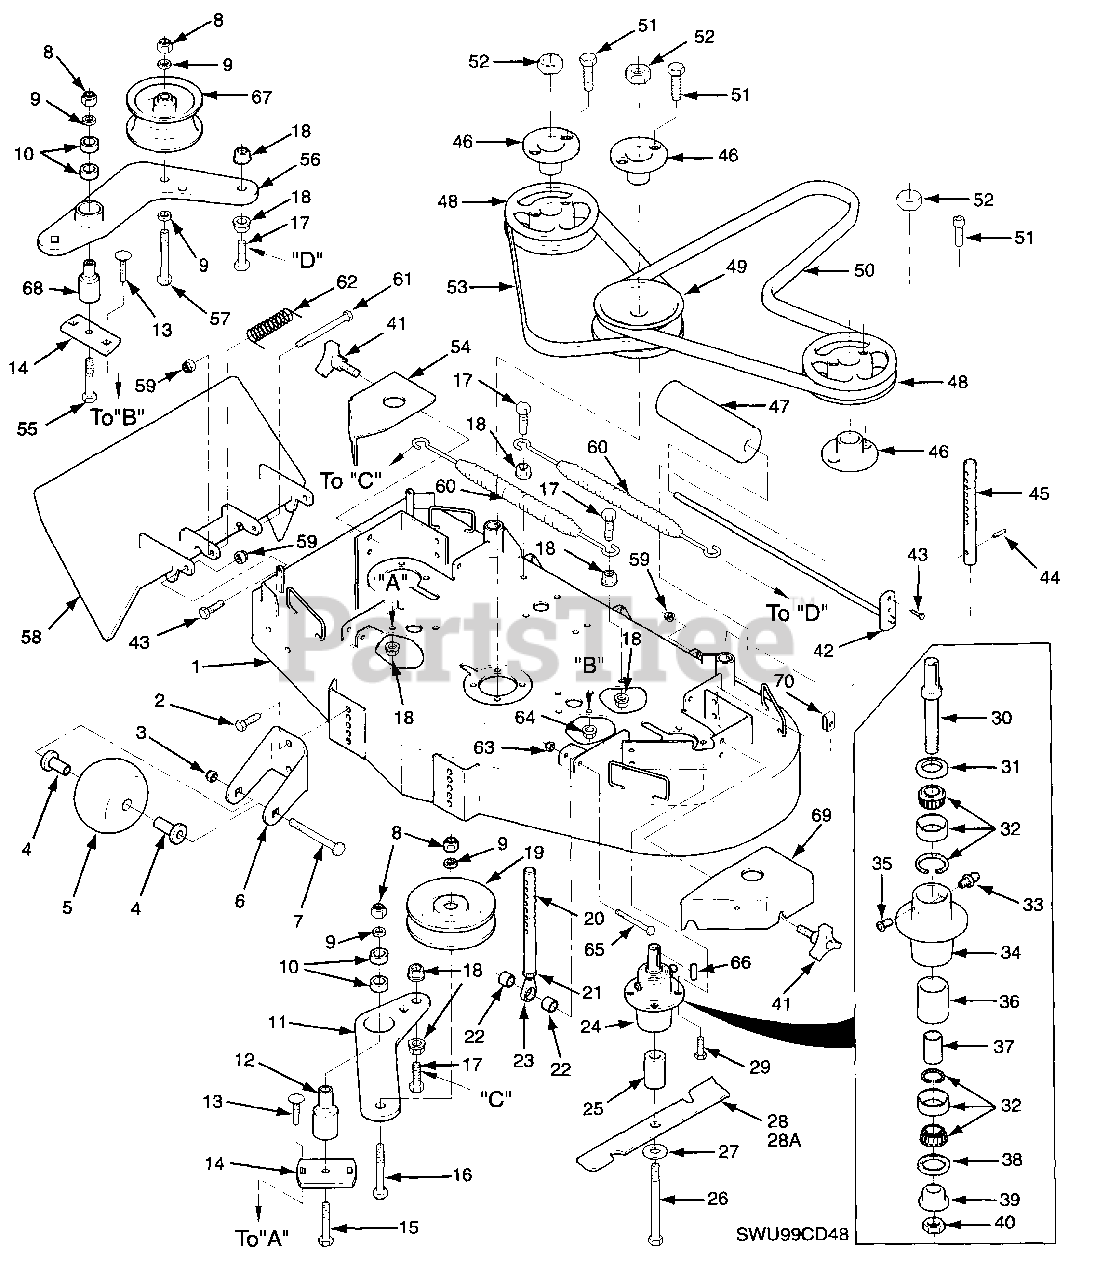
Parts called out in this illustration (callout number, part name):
1	Cutter Deck With Decals
2	Capscrew, 3/8-16 x 1.0" Serrated Flange
3	Lock Nut, 3/8-16 Center Lock
4	Bushing, 376 ID Oilite
5	Wheel, Anti-Scalp
6	Bracket, Anti-Scalp Wheel
7	Bolt, Carriage 3/8-16 x 4.0"
8	Hex Nut, 3/8-16 Elastic Stop
9	Flatwasher, 3/8 (.938 x .391 x .105)
10	Ball Bearings
11	Idler Arm RH
12	Pivot, Idle - Short
13	Bolt, Carriage 5/16-18 x 1.0"
14	Base, Idler Pivot
15	Capscrew, Hex Head 3/8-16 x 2.50"
16	Capscrew, Hex Head 3/8-16 x 2.0"
17	Capscrew, Hex Head 3/8-16 x 1.50"
18	Nut, 3/8-16 Serrated Flange
19	Pulley, Idler
20	Pin Assembly
21	Nut, 3/8-24 Jam
22	Spacer, Deck Adjustment Pin
23	Rod End, Male 3/8-24
24	Spindle Assembly
25	Spacer, Spindle
26	Bolt,Hex Head 5/8-11 x 9.50"
27	Flatwasher, 5/8 W
28	Cutter Blade 16-1/2"
28A	Cutter Blade 16-1/2" Hi Lift
29	Bolt, Hex Head 5/16-18 x 1.25"
30	Spindle Shaft
31	Seal, Cutter Spindle - Top
32	Tapered Bearings (Two)
33	Grease Fitting
34	Spindle Housing
35	Relief Fitting, Cutter Spindle
36	Spacer Outside
37	Spacer, Inside
38	Seal, Cutter Spindle - Bottom
39	Spindle Bushing
40	Nut, Spindle
41	Wing Nut, 3/8-16
42	Roller Shaft
43	Bolt, Hex Head 5/16-18 x 1.0"
44	Pin, Slotted Spring 3/16 x 1.50"
45	Pin, Deck Adjustment Rear
46	Tapered Hub
47	Guide, Roller
48	Pulley
49	Pulley, 5 75 Double Grove
50	Belt, Deck Drive
51	Capscrew, Socket Head 1/4-20 x 1 375"
52	Hex Nut, 5/8-11
53	Belt, Cutter Deck
54	Belt Cover, RH
55	Capscrew, Hex Head 3/8-16 x 3.25"
56	Idler Arm Weldment
57	Capscrew, Hex Head 3/8-16 x 3.75"
58	Discharge Chute
59	Nut, 5/16-18 Serrated Flange
60	Spring, Deck Idler
61	Bolt, Hex Head 5/16-18 x 4.25"
62	Spring, Chute Return
63	Nut, 3/8-16 Elastic Stop
64	Nut, 5/16-18 Serrated Flange
65	Bolt, Hex Head 3/8-16 x 2.50"
66	Key, 1/4 x 1/4 x 2.0"
67	Pulley, Idler
68	Pivot, Idler - Long
69	Belt Cover LH
70	U-Nut, 3/8-16
